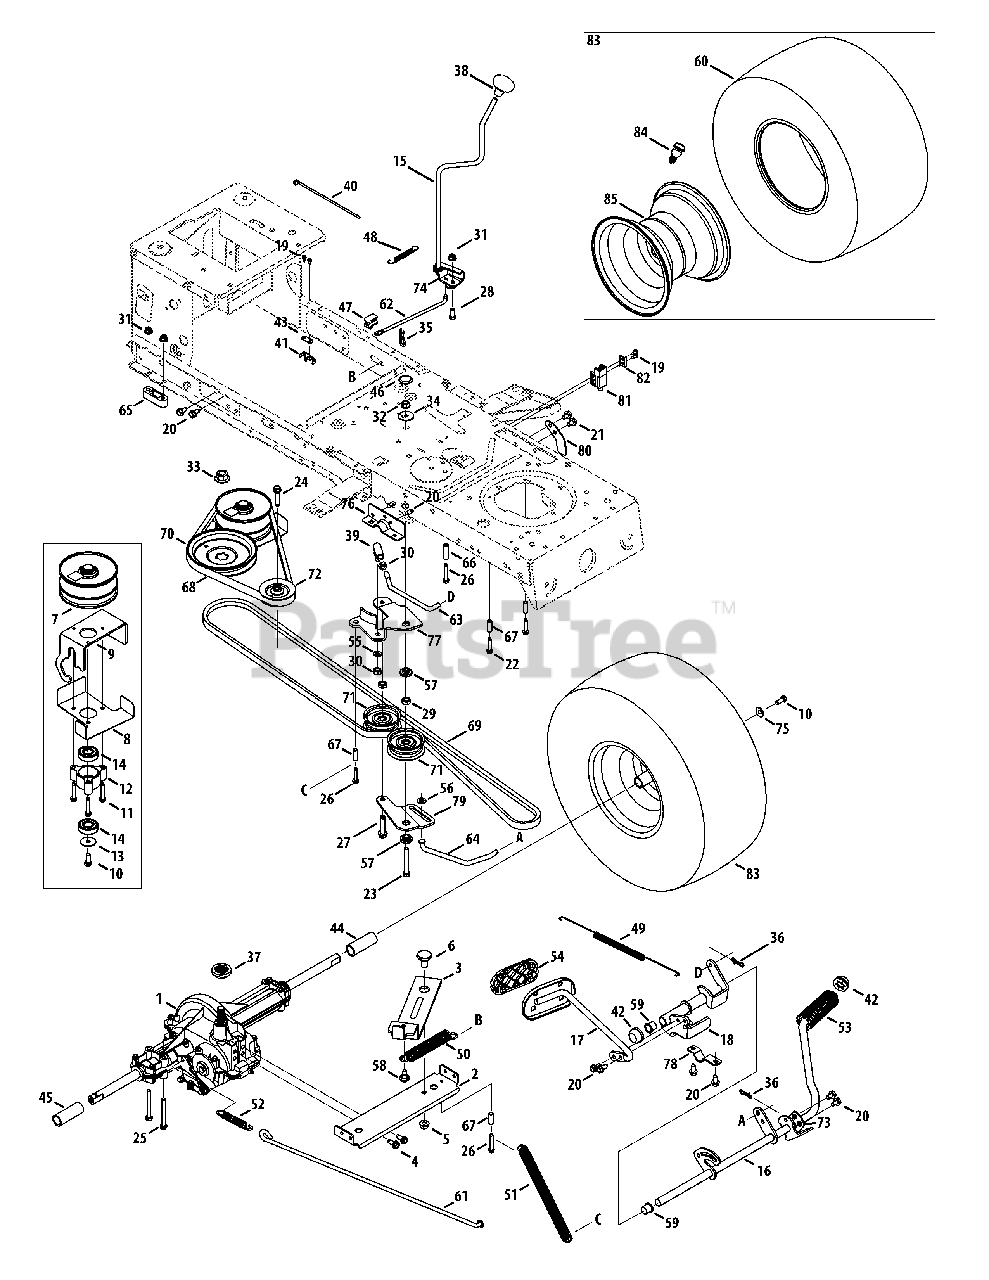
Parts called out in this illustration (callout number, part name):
1	Dr Assembly, Autodrive Lt-5
2	Auto-drive Bracket Assembly
3	Idler Bracket Assembly
4	Tap Screw, 5/16-18 x 0.750
5	Flange Lock Nut, 3/8-16
6	Shoulder Screw, .625 x .217
7	Pulley Assembly, Var. Spd. 4.75 Od
8	Belt Keeper Assembly
9	Variable Bracket Assembly
10	Hex Screw 5/16-24 .750
11	Tap Screw, 1/4-20 1.500
12	Bearing Cup
13	Wash, Flat .330 X 1.25 X .06
14	Ball Bearing, 17 x 40 x 12.6203
15	Lvr Assembly, Shft
16	Ped Assembly, Drive, Autodrive
17	Ped Assembly, Cont, Autodrive
18	Bracket Assembly, Pedal, Autodrive
19	Screw, Ab, #8-18, 0.500
20	Screw, Tt, 5/16-18, .750
21	Screw, Tt, 5/16-18, 0.625
22	Screw, Tt, 1/4-20, 1.250
23	Hex Hd. Screw, 3/8-16, 2.50
24	Screw, Ttsems, 3/8-16, 1.500
25	Hex Hd. Screw, 5/16-18, 3.50
26	Screw, Tt, 1/4-20, 1.625,
27	Screw, Tt, 3/8-16 x 1.75
28	Hex Hd. Screw, 5/16-18, .75
29	Nut, Jam, 7/16-20
30	Nut, Hex, 3/8-24
31	Nut, Flange Lock Nut, 5/16-18
32	Nut, Flange Lock Nut, 3/8-16
33	Nut, Flg, 9/16-18
34	Wash, Flat, .406 x 1.920 x .060
35	Pin, Cotter Int- .125 Dia
36	Pin, Cot, Bow-Tie 72
37	Hub, Pulley, 5/8 Spline
38	Knob, Shft
39	Ball, Joint
40	Cable, Tie, 3/16 X .05 X 7.4
41	Switch, Spring, Short
42	Cap, Push 5/8
43	Plate, Insulator Nut
44	Sleeve, .758 X .821 X 3.3125
45	Sleeve, .758 X .821 X 2.4375
46	Plug, Deck Hole, 7/8
47	Shift Plate Bearing
48	Spring, Ext, .38 Od X 3.25 Lg
49	Spring, Extn, .70 Dia X 12.00 Lg
50	Spring, Extn, .97 Od X 6.18 Lg
51	Spring, Extn, .56 X 12.05 x .068
52	Spring, Extn, .59 Od X 4.00 Lg
53	Pad, Foot, 4.0 Long
54	Pad, Cont
55	Wash, Lock, 3/8, Regular Duty
56	Wash, Flat, .375 X .738 X .063
57	Spacer, Shoulder, 1.00 X .38 X .38
58	Screw, Shoulder, .43x.29, Tt, 5/16-18
59	Bearing, Flg, .630 Idx .695 Od X .60
60	Tire, 20 x 8 x 8 Sq. Sh.
61	Rod, Brake, Lt-5 Trans
62	Rod, Shift, Lt-5 Stretch 46"
63	Rod, Adj, Idlr, 3/8
64	Rod, Trans, Footpedal Bypass
65	Spacer, T-Axle .68
66	Spacer, .260 X .372 X 1.420 Lg
67	Spacer, .260 X .375 X 1.030 Lg
68	Belt, V Typ, 5l X 40.9 Lg Poly
69	Belt, V Typ, 5l, 90.80, Poly
70	Pulley, Idlr, Flat 7.25 Od
71	Pulley, Idlr, Flat 2.75 Od
72	Pulley, Idlr, V-Type X 3.06
73	Bracket, Ped, Support Lt-5
74	Bracket, Shft, Adj
75	Bell Washer, .340 x .872 x .060
76	Bracket, Ped, Frame Rh
77	Bracket, Idlr, Dbl Autodrive
78	Bracket, Supt, Pedal Stap
79	Bracket, Idlr, Center Dbl
80	Pedal Stop Plate
81	Interlock Switch
82	Switch Plate
83	Wheel Assembly, 20 x 8 x 8 Sq. Sh.
84	Valve Stem
85	Rim Assembly
